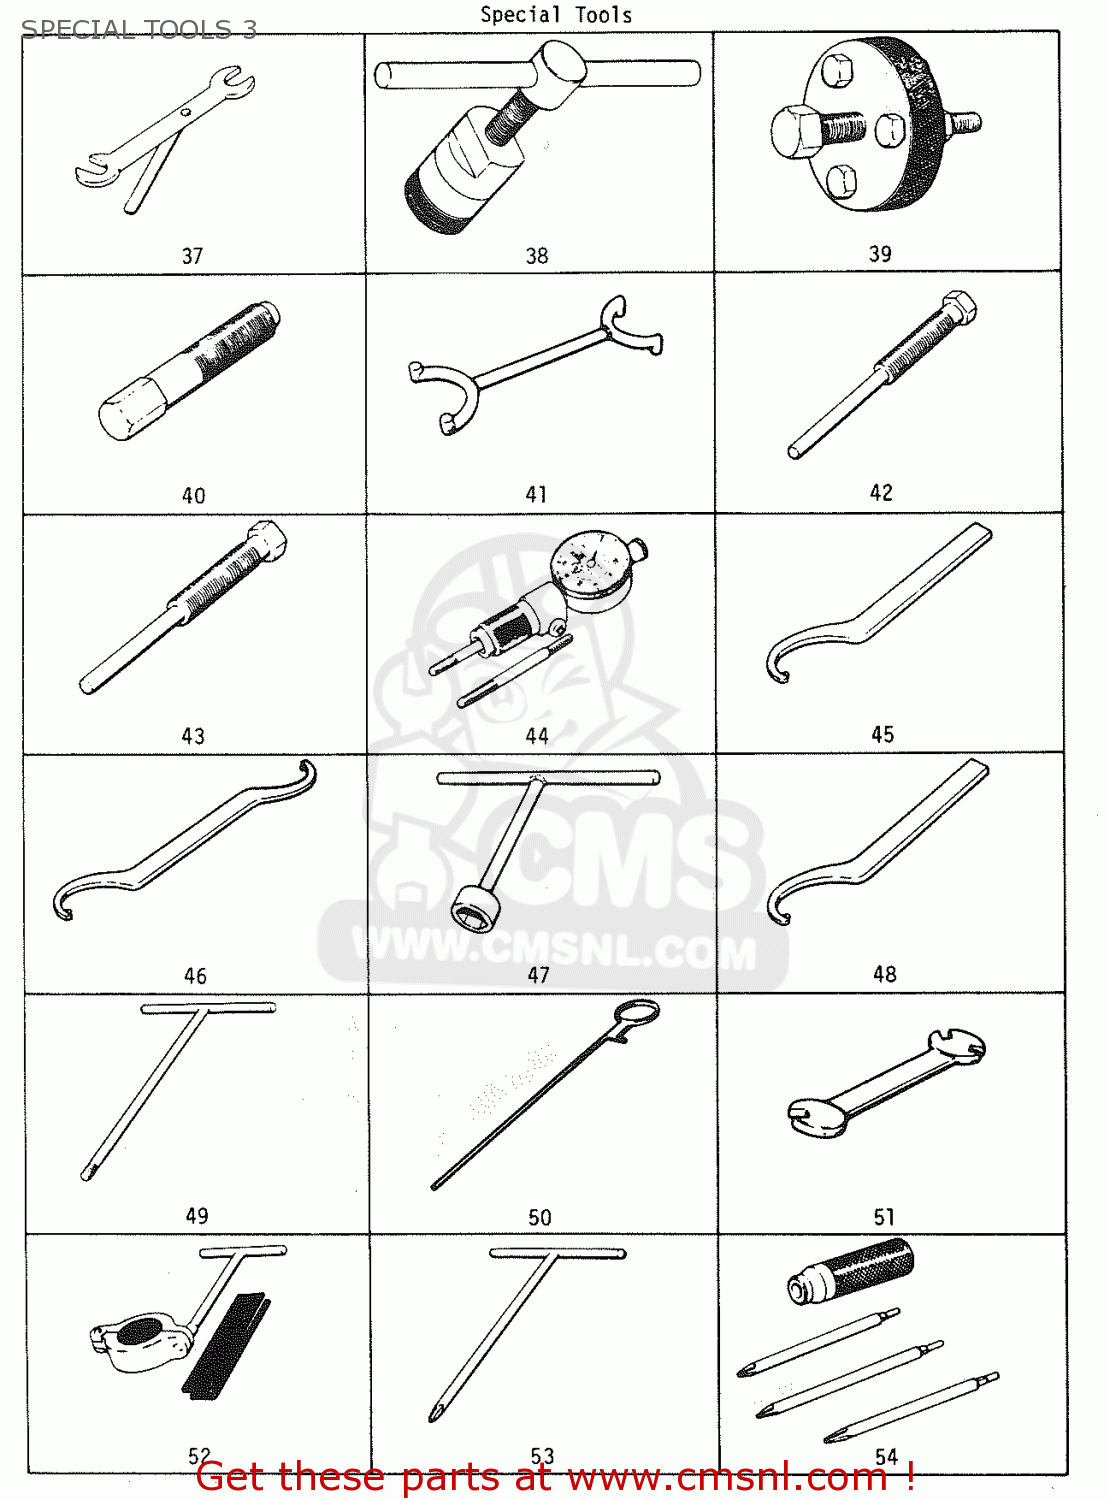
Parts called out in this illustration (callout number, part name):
37	WRENCH, CONTACT POINT
39	ROTOR REMOVER
41	ROTOR HOLDER
44	TIMING GAUGE
46	STEERING STEM NUT WRENCH
48	STEERING STEM LOCK NUT WRENCH
49	FRONT FORK ASSE
50	FRONT FORK OIL
51	SPOKE NIPPLE WRENCH
52	FRONT FORK OUTER TUBE NUT WRENCH SET
53	T TYPE CROSS HEAD SCREW DRIVER (6MM)
54	MAGIC SCREW DRIVER SET (FOR UNSCREWING)
